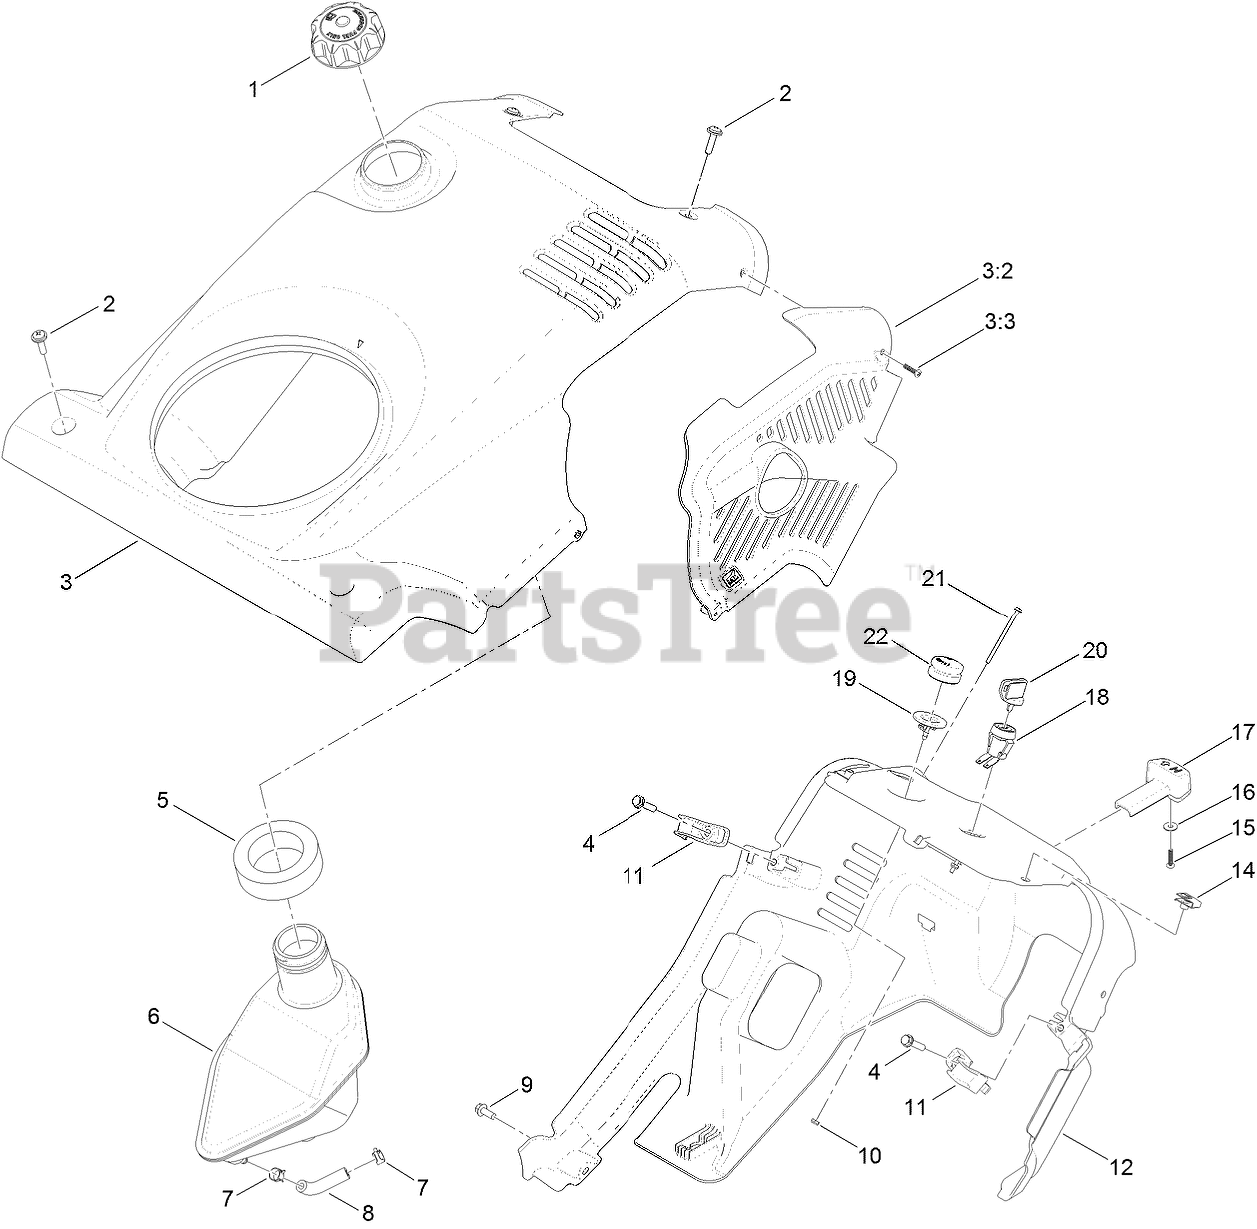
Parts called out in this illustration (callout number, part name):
1	CAP-GAS
2	SCREW-PPH
3	SHROUD ASM
3:2	BAFFLE-EXHAUST
3:3	SCREW-PPH
4	SCREW-PLASTITE
5	SEAL-TANK
6	TANK-FUEL, GAS
7	CLAMP-HOSE
8	HOSE-FUEL
9	SCREW-HWH
10	NUT-HEX
11	CLIP-SHROUD
12	SHROUD-LOWER
15	SCREW-PPH
16	WASHER-PLAIN
17	KNOB-CHOKE
18	SWITCH
19	BODY-PRIMER
20	KEY-IGNITION
21	SCREW-HWH
22	BULB-PRIMER
